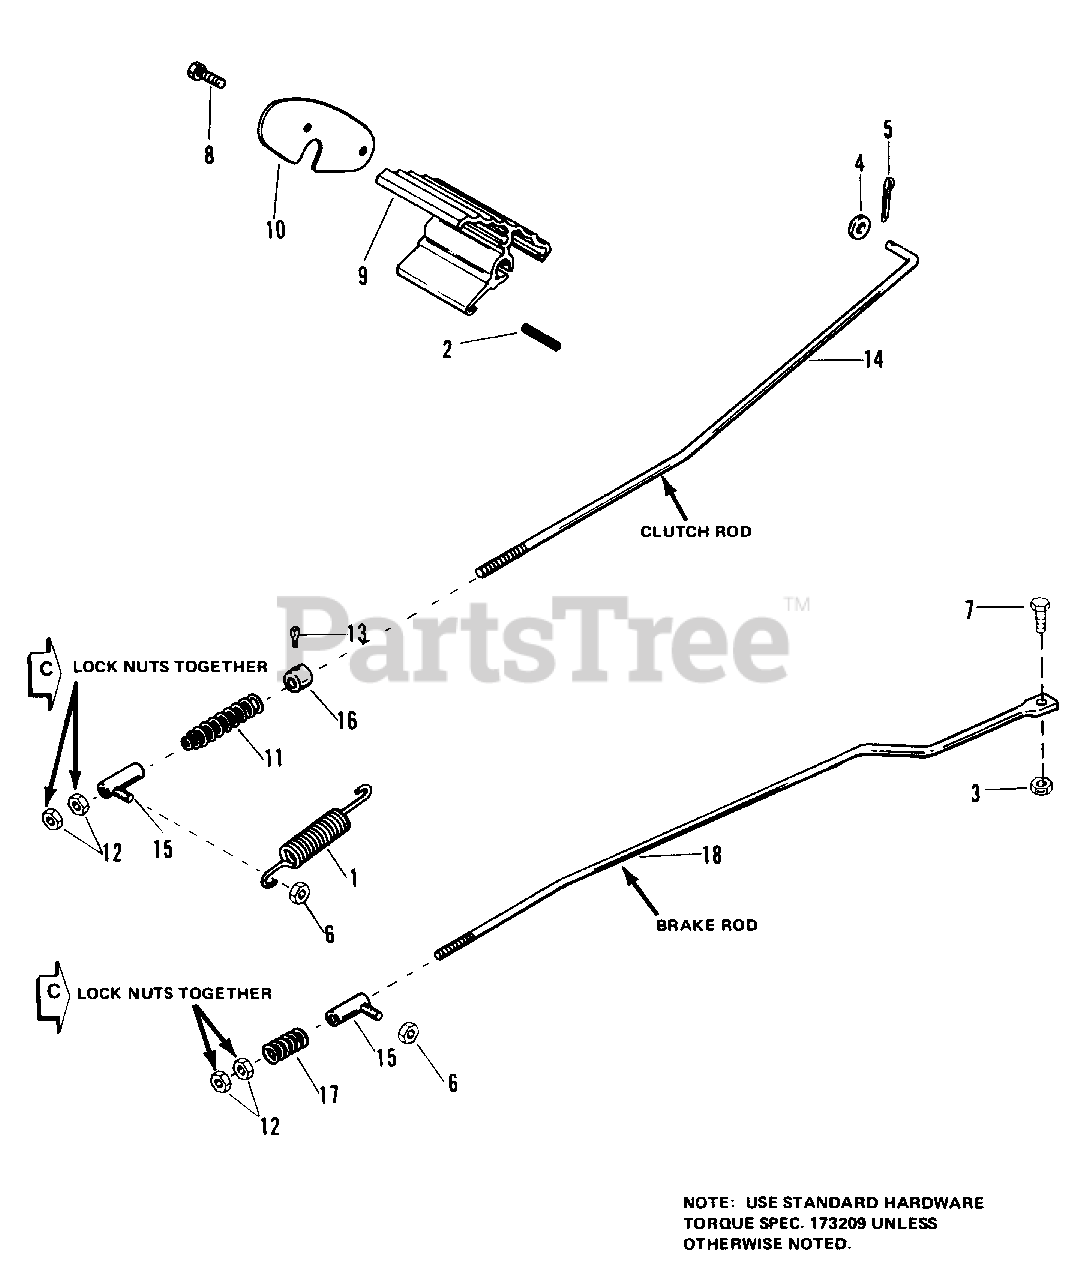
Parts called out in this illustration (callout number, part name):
1	SPRING, Return
3	NUT, Center Lock, 1/4-20
4	WASHER, Plain 1/4
5	PIN, Cotter 3/32 x 3/4
6	LOCKNUT, Hex 5/16-18
7	CAPSCREW, Hex Hd., 1/4-20 x 3/4
8	SCREW, Hex Washer Hd., 1/4-20 x 5/8
9	PEDAL, Foot
10	PLATE, End
11	SPRING, Compression
12	NUT, Hex, 5/16-18
13	SCREW, Set Sq. Hd. Cup., 1/4-20 x 3/8
14	ROD, Clutch
15	GUIDE ASSY., Rod
16	COLLAR, Set
18	ROD, Brake
